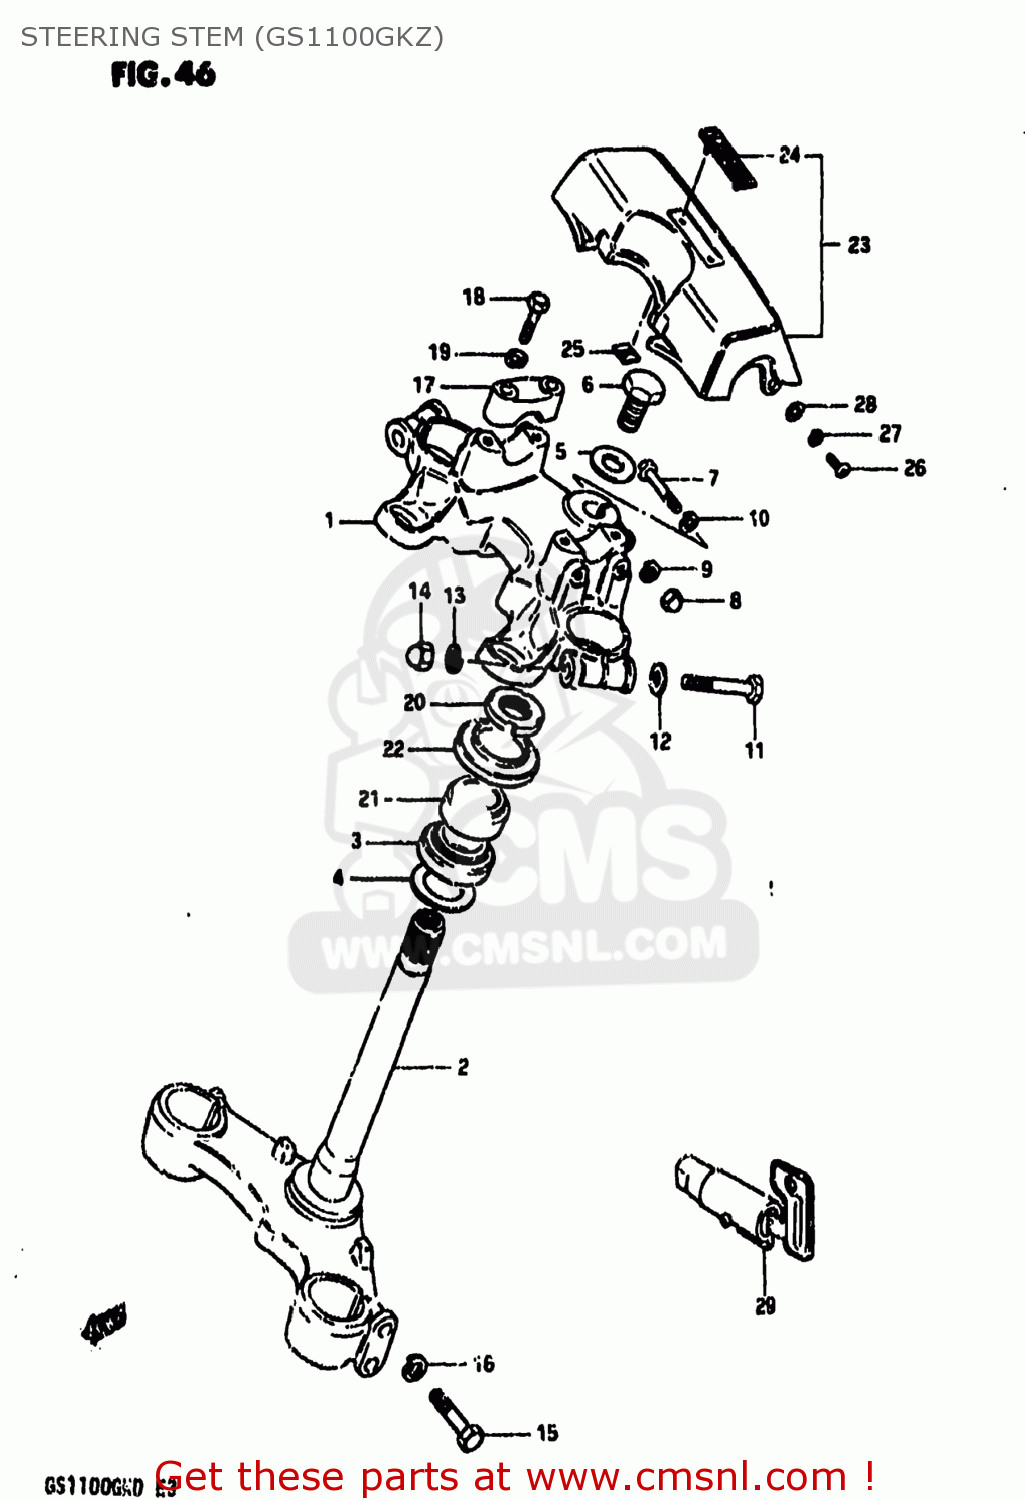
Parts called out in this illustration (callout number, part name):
1	HEAD,STEERING STEM
2	STEM,STEERING
3	BEARING
4	WASHER,THRUST
5	WASHER,STEERING STEM
6	NUT,STEM HEAD
7	BOLT 8X50
8	NUT
9	LOCK WASHER
10	WASHER
11	BOLT 10X55
12	WASHER
13	LOCK WASHER
14	NUT, LOWER LH
15	BOLT 8X40
16	LOCK WASHER
17	HOLDER,HANDLE(BLACK)
18	BOLT
19	LOCK WASHER
20	NUT,STEERING STEM
21	TAPER,ROLLER BEARING
22	DUST SEAL,STEERING UPR
23	PAD,HANDLEBAR
24	EMBLEM,HANDLE COVER PAD
25	NUT
26	SCREW
27	LOCK WASHER
28	WASHER
